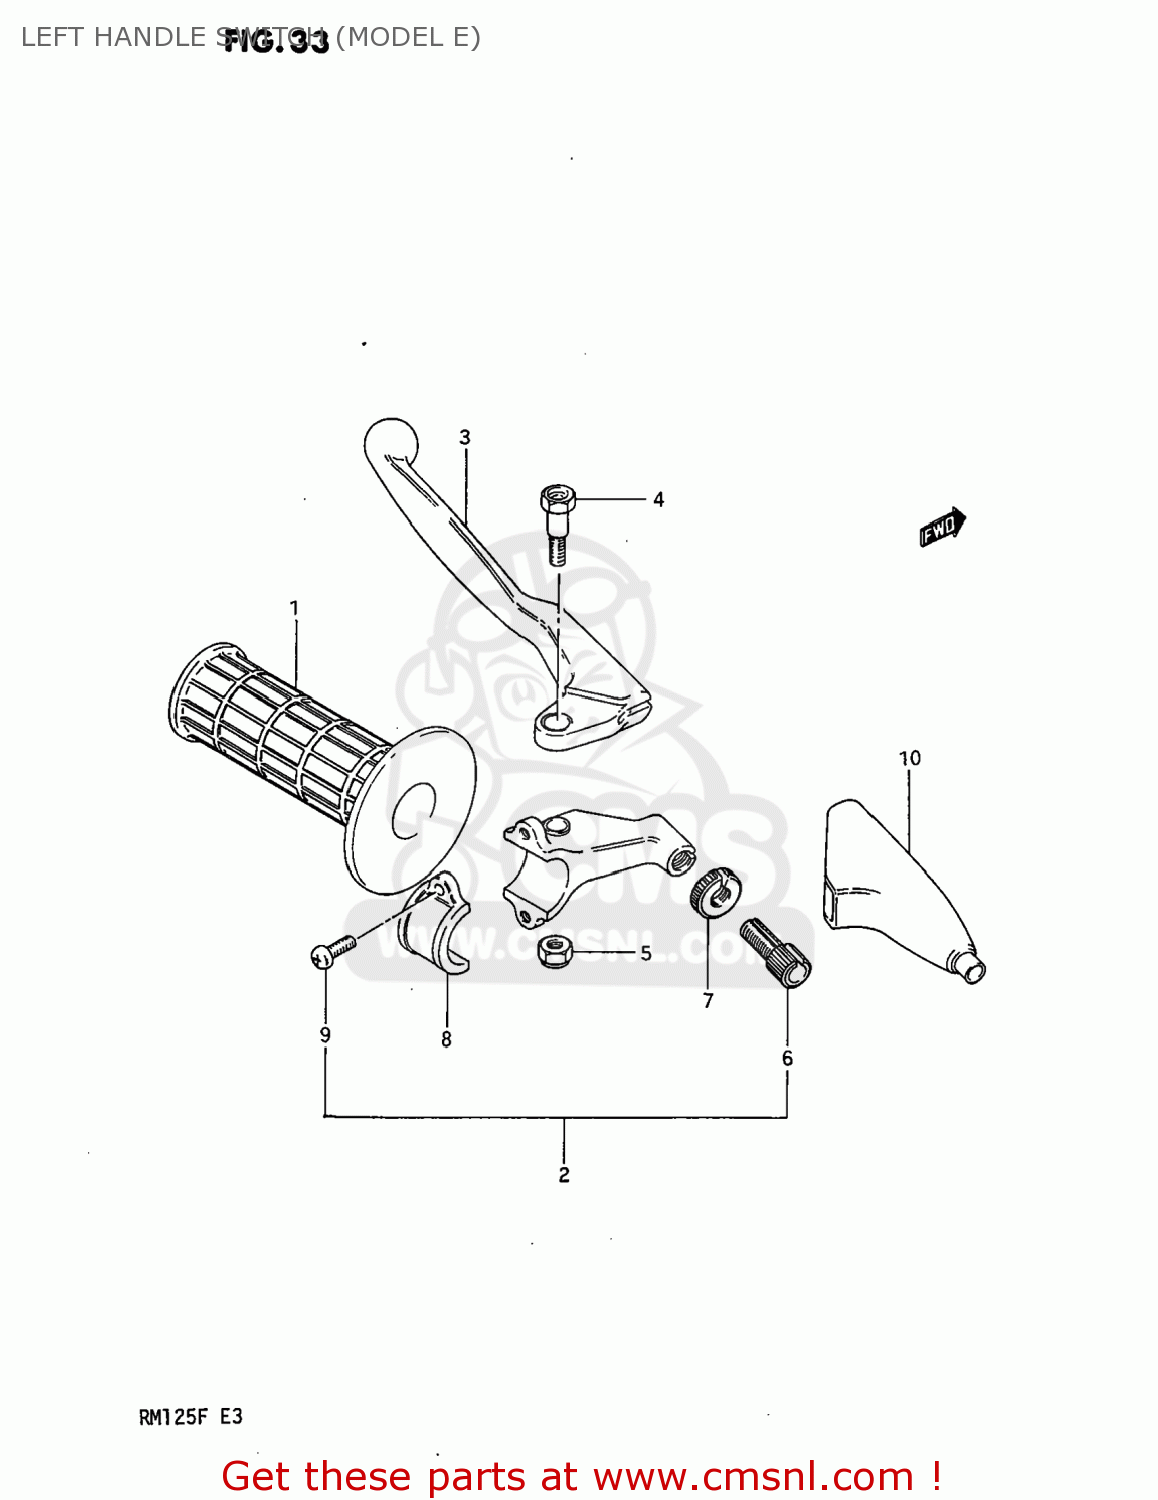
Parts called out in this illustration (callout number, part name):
1	GRIP,LEFT
2	LEVER ASSY,CLUTCH
3	LEVER,CLUTCH
4	BOLT,LEVER
5	NUT 6MM
6	ADJUSTER,CABLE
7	NUT,CABLE ADJUSTER
8	BRACKET,CLUTCH LEVER HOLDER
9	SCREW
10	COVER,CLUTCH LEVER
